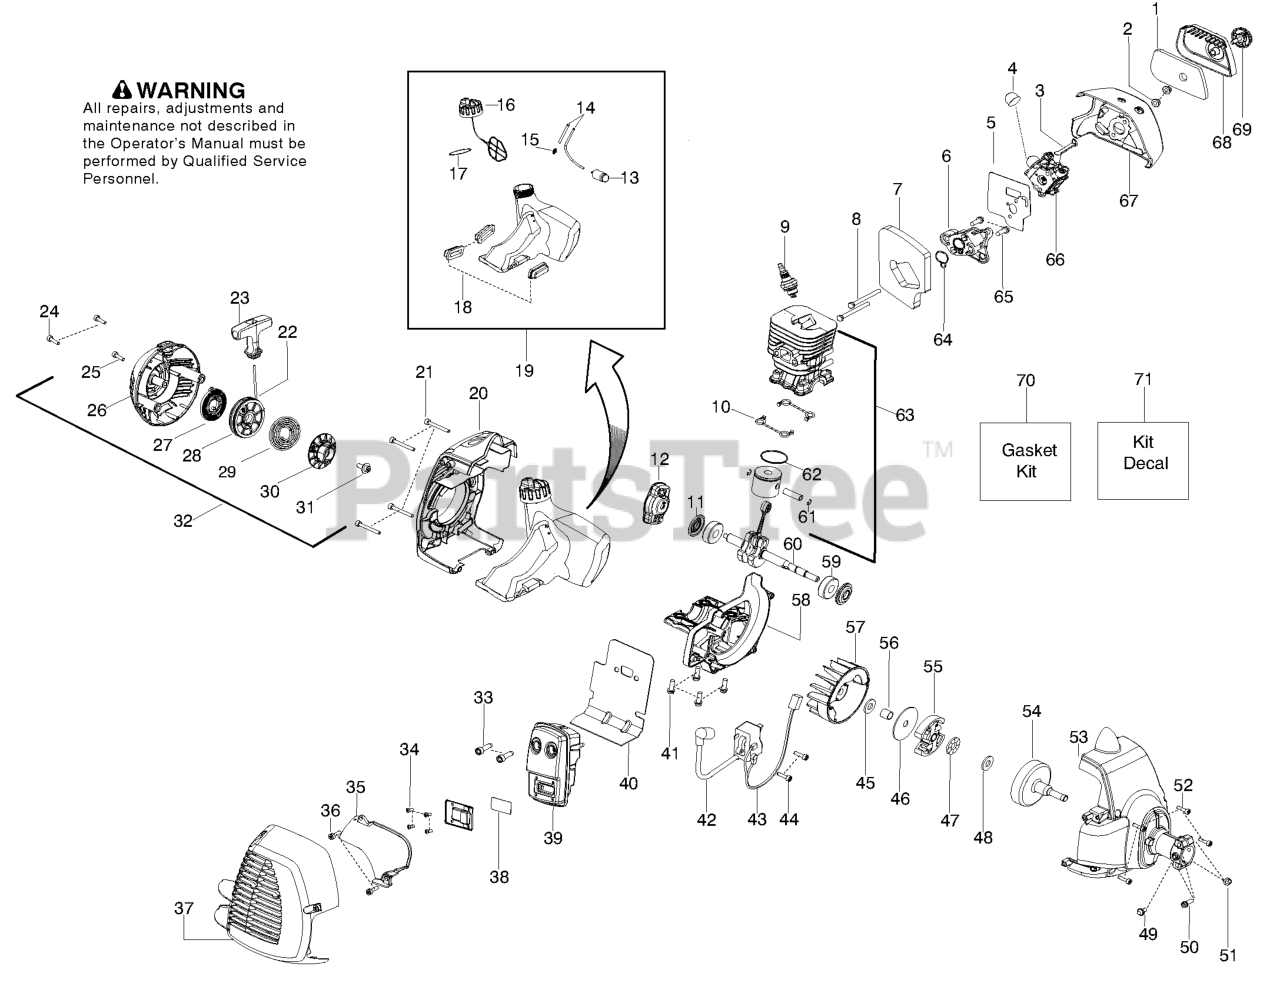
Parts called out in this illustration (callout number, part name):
1	FILTER AIRBOX
3	CHOKE LEVER
4	PURGE BULB ZAMA
5	KIT GASKET CARB 28CC
6	CARB ADAPTOR
7	KIT GASKET 28CC
8	BOLT CARB ADAPTOR
9	Plug - Spark (RCJ-8Y)
10	Seal - Cylinder (kit)
11	KIT GASKET 28CC
12	Assy - Starter Pawl
13	FUEL PICK-UP ASSY
14	Kit - Fuel Line
15	Fitting - Fuel line
16	ASSY-CAP W/RETAINER
17	KIT GASKET 28CC
18	ISOLATOR FUEL TANK
19	Kit - Fuel Tank Assy.
20	KIT STARTER HSG HVA 128
22	Kit - Rope
23	Handle - Starter
24	SCREW M5-0.8X30MM
25	SCREW M4 X 1.75 PT 16MM
26	Hsg. - Starter w/eyelet
27	Kit - Spring
28	Kit - Starter Pulley
29	Spring - Driver
30	Pulley - Driver
32	Assy - Starter Hsg.
33	BOLT MUFFLER
34	SCREW-6-19X5/16PLAST PA
35	SHIELD HEAT
36	SCREW M4 X 1.75 PT 16MM
37	KIT MUFFLER GUARD HVA
38	KIT SPARK ARRESTOR SCREEN
39	KIT MUFFLER LE28
40	KIT GASKET 28CC
41	SCREW-M5-0.8 X 25MM(TAP)
42	IGNITION MODULE MBU-7
43	ASSY MODULE LEAD WIRE
44	SCREW M4 X .70 TT 16MM
45	WASHER CLUTCH
46	WASHER-CLUTCH
47	BEARING THRUST
48	WASHER THRUST
49	Screw
50	Screw
51	LOCKNUT-HEX 10-24
52	SCREW M4 X .70 TT 16MM
53	Assy - Fan Housing
54	ASSY-CLUTCH DRUM
55	ASSEMBLY CLUTCH
56	SPACER FLYWHEEL
58	Crankcase - Cast
59	BEARING RADIAL BALL (6201)
60	Assy - Crankshaft
61	WRIST PIN RET.
62	RING PISTON
63	Kit - Piston/Cyl.
64	KIT GASKET 28CC
65	SCREW-M5-0.8 X 25MM(TAP)
66	KIT CARB
67	RP_AIR BOX
68	COVER-AIR BOX
69	KNOB ASSY AIRBOX COVER
70	KIT GASKET 28CC
